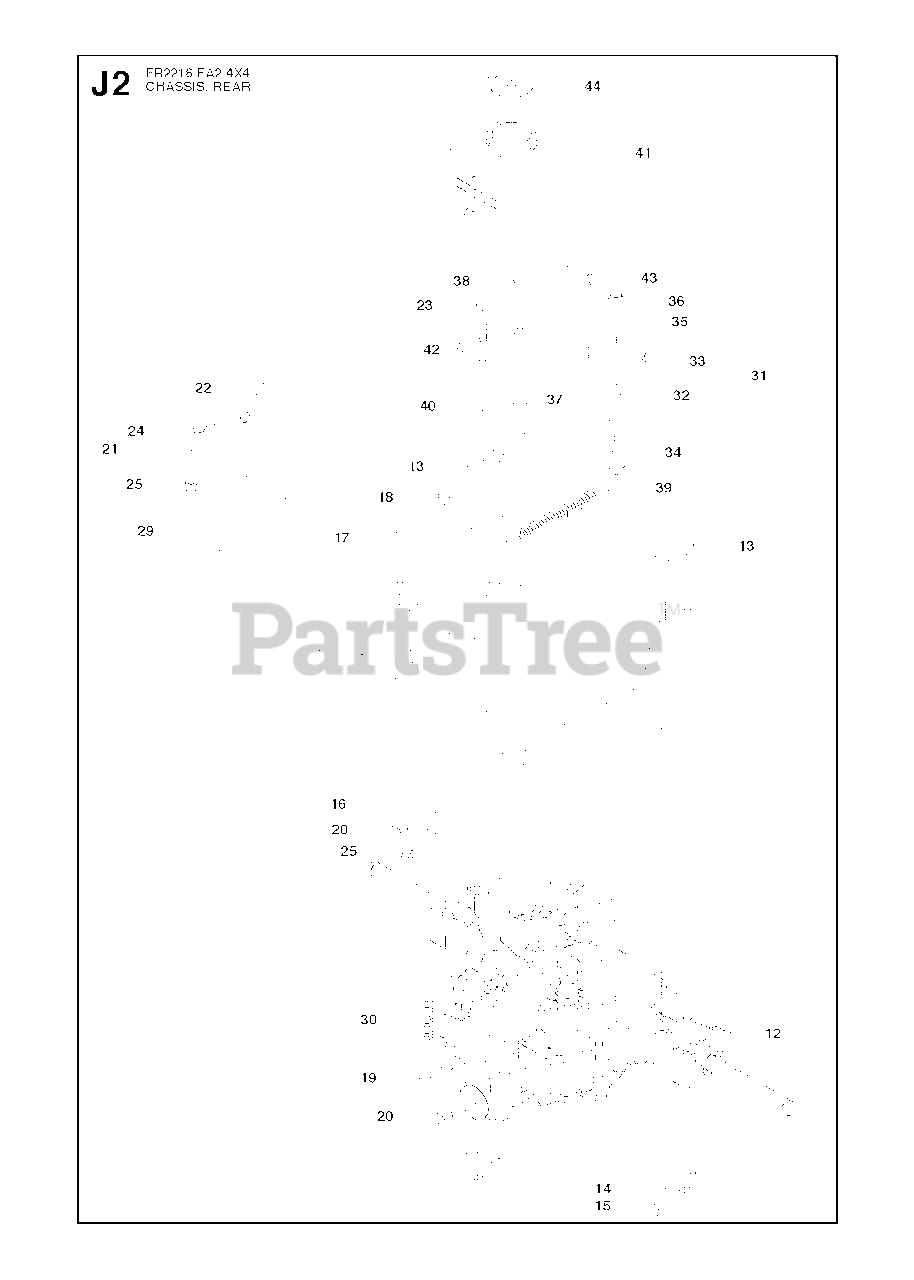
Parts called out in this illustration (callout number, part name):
12	HYDRAULMOTOR
14	WASHER BRB 8.4X17
15	NUT
19	CONNECTOR
20	NUT
22	WASHER
25	LOCKNUT M5
30	SPRING
31	TENSIONER
32	TENSIONER
33	PULLEY
34	SCREW
35	SPACER
36	LOCKNUT M8
37	WASHER
38	SCREW 8X20
